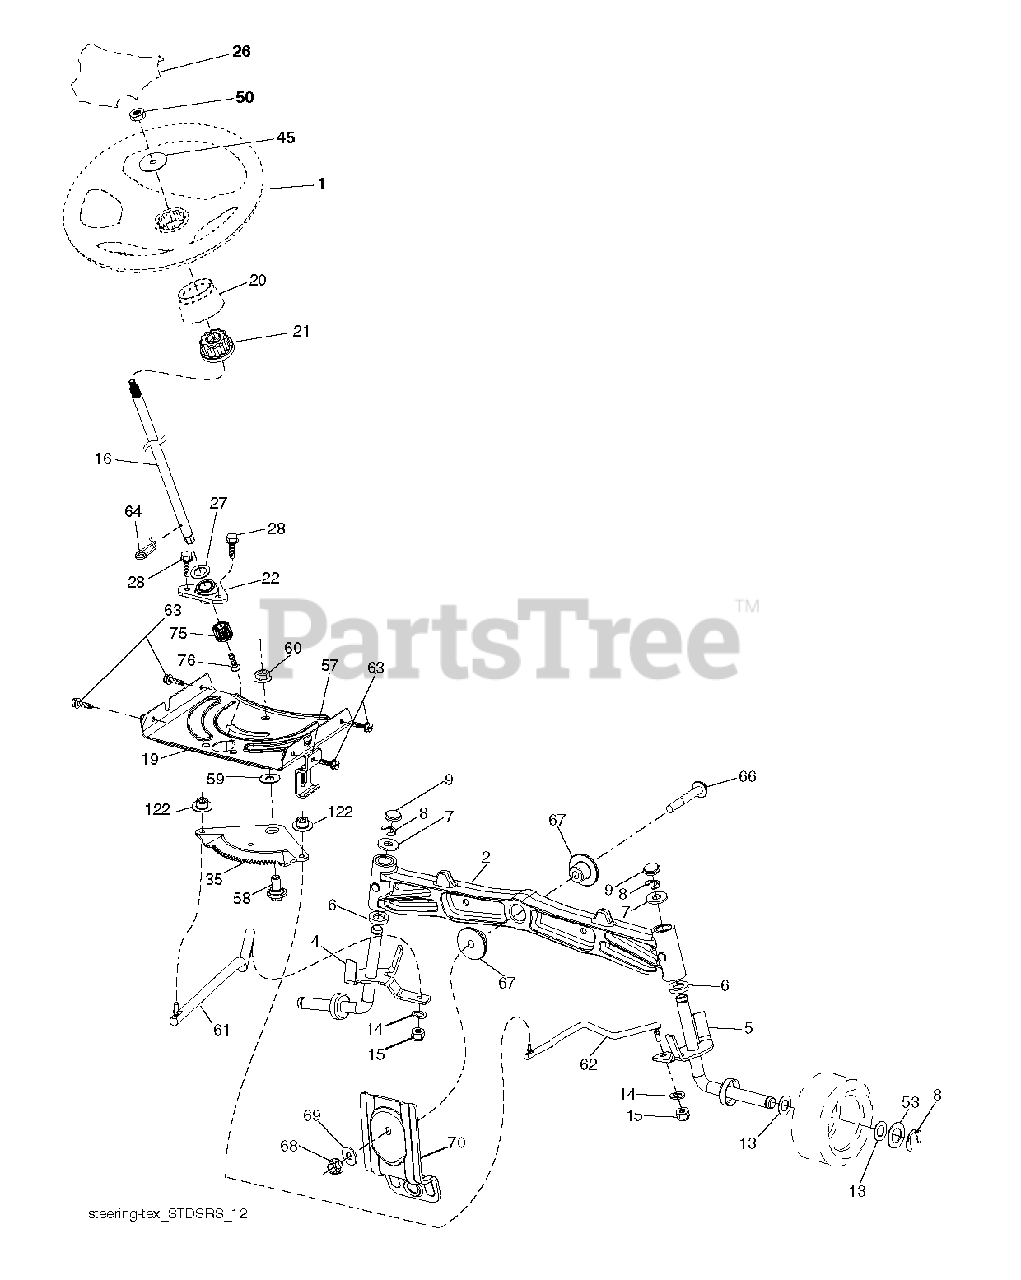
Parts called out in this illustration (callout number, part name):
1	WHEEL.STEERING.MLT.BR.YEL/OVRM
2	AXLE.CAST.IRON
4	SPINDLE.WELDED.LH.16"TEX
5	SPINDLE.WELDED.RH.16"TEX
8	RING CLIP
9	CAP.SPINDLE.BLACK
14	WASHER, LOCK 3/8
15	NUT CROWNLOCK 3/8-24
19	PLATE.STEER.DDL.NLT/NG
20	BOOT.STRNG.PREDATOR.YT/GT.428
26	CAP.WHL.STRNG.MULTI.BRND.YEL
27	WASHER LT
28	SCREW, 3/8-16X3/4
35	GEAR.SECTOR.PLATE.DDL.
45	WASHER.3/8ID.2-3/8OD.12GA.PLTD
50	NUT LOCK FLG 3/8-16 UNC
53	WASHER.HARDENED
57	BRKT.UPSTOP.GT/LT.TEX
58	BOLT.SHOULDER.SECTOR.P
59	WASHER.THURST.SECTOR.S
60	NUT FLANGE LOCK 5/8-11
61	DRAGLINK.LH.BALLSTUD.D
62	DRAGLINK.RH.BALLSTUD.D
63	SCREW
64	RETAINER.CLIP.SPRING.S
66	BOLT HEX FGHD 7/16-14 X 3 SERR
67	BUSHING.PM.FRONT AXLE
68	NUT.LOCK.FLANGE.7/16
69	WASHER.1.5X.505X.118
70	Deck Suspension Bracket, Front RR
76	Screw Head Socket Lrvb
122	CAP.GEAR.SECTOR.TEX
